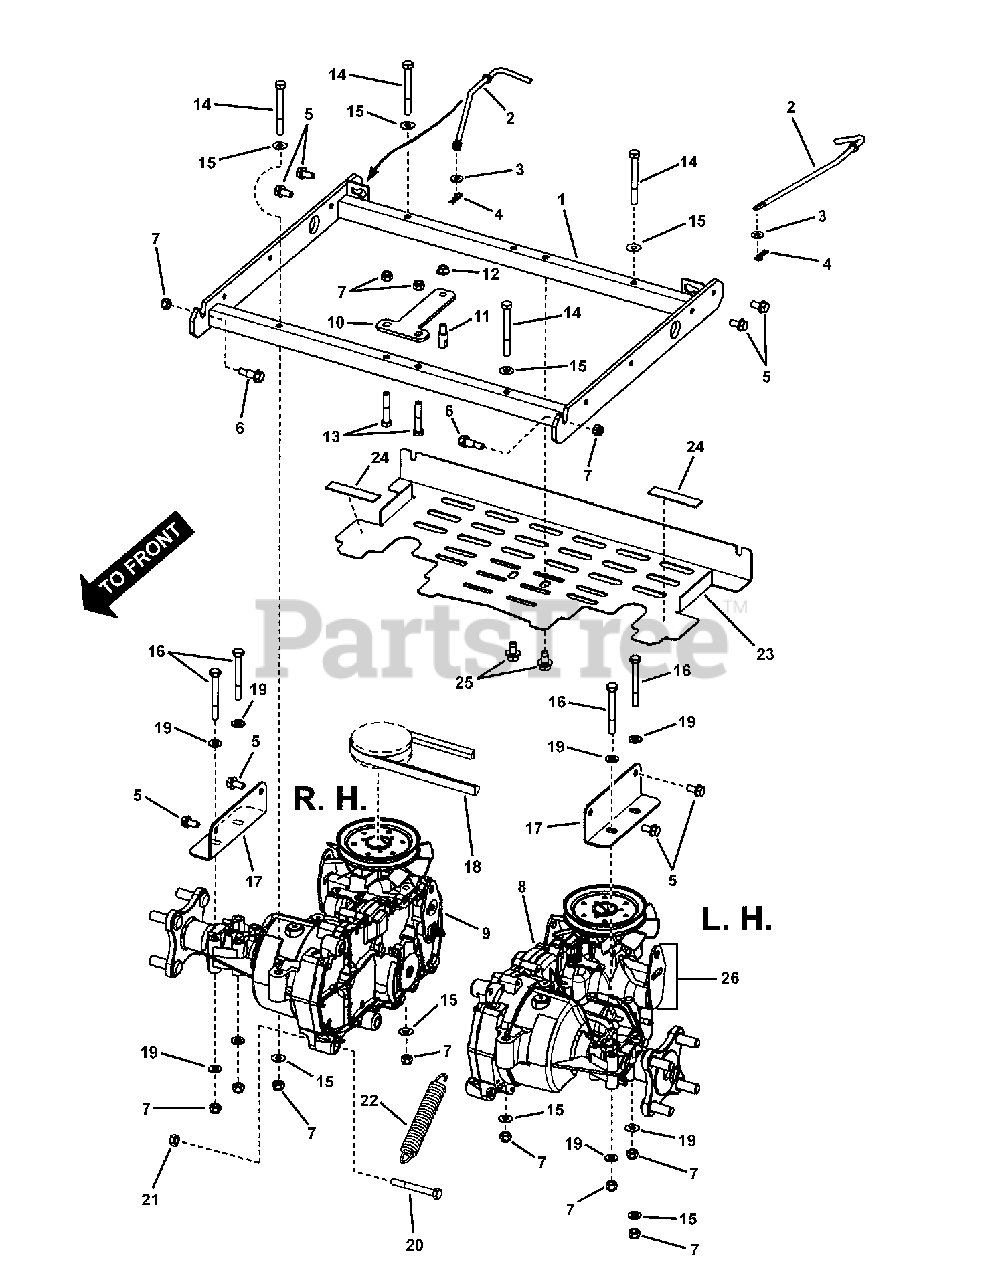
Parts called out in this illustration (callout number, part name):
1	WELDMENT, Transaxle Support
2	ROD, Roll Release
3	WASHER, .28 x .63 x .06 Flat, GR 5
4	HAIR PIN, 1-1/8"
5	SCREW, 5/16-18 x 3/4" Hex Washer Self-Tap
6	SHOULDER BOLT, 5/16-18
7	NUT, 5/16-18 Hex Nyloc
8	TRANSAXLE, LH RZT
9	TRANSAXLE, RH RZT
10	BRACKET, Anti-Rotation
11	PIN, Anti-Rotation, RZT Clutch
12	NUT, 5/16-18 Hex Flange Lock, GR 5
13	SCREW, 5/16-18 x 1-3/4" Hex Head Cap, GR 5, YZ
14	SCREW, 5/16-18 x 3" Hex Head Cap, GR 5, YZ
15	SHIM WASHER, 5/16" I.D.
16	SCREW 5/16-18 x 2-3/4" Hex Head Cap, GR 5, YZ
17	BRACKET, Transaxle Support
18	V-BELT, HA Sect. (wrapped) 58.00 effective length
19	WASHER, .34 x .69 x .08 Flat
20	SCREW, 7/16-20 x 2-1/2" Hex Head Cap, GR 5 (Special Head)
21	NUT, 7/16-20 Hex Center Lock Jam, GR 5 or B
22	SPRING, Extension, .562 OD x 4.250 long x .049 Wire B
23	GUARD, Euro 44
24	PAD, Rubber Adhesive
25	SCREW, 3/8-16 x 5/8" Hex Washer Self-Tap
26	ARM, Control Kit
